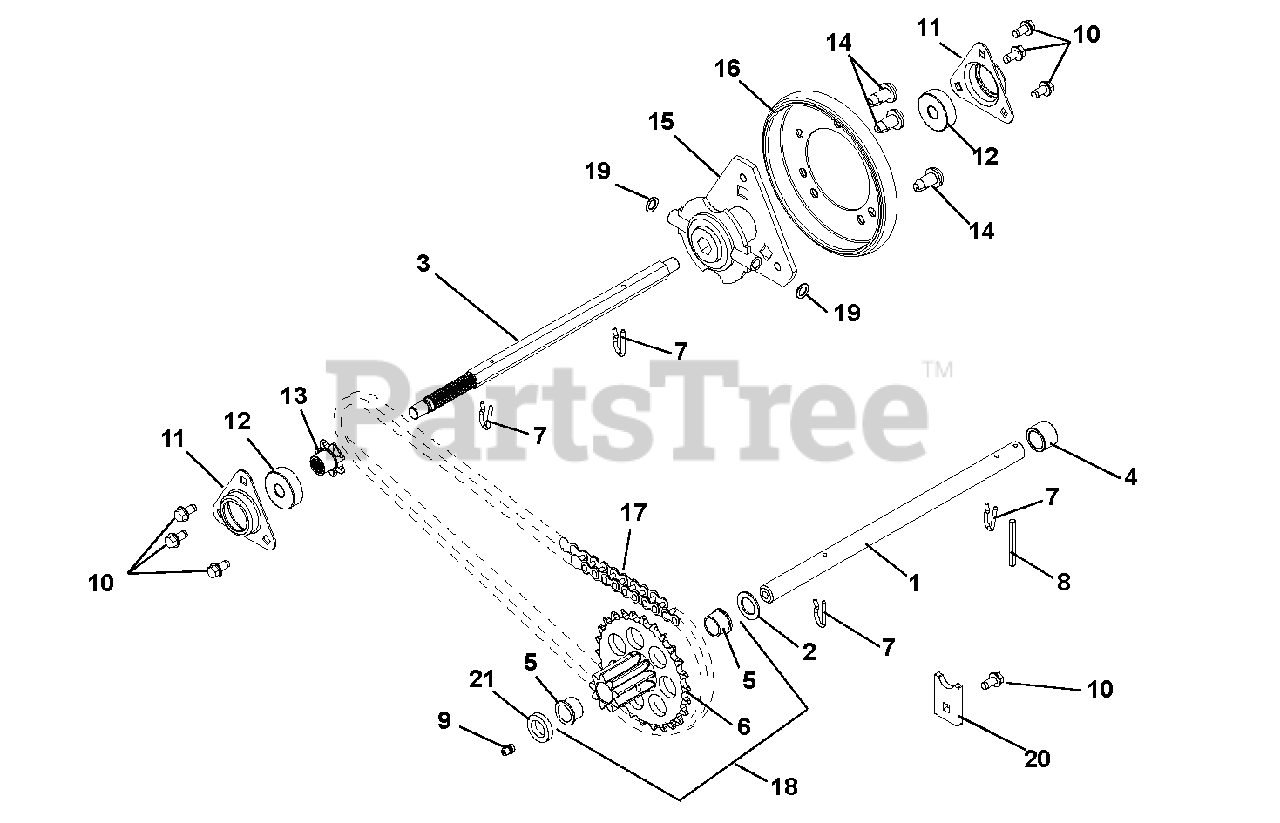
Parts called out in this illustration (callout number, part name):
1	Shaft, Pinion
2	Washer, Flat Steel .630 x 1.005 x .062
3	Shaft, Hex
5	Bushing, Flange (Included in Item 18)
6	Sprocket/Gear (Included in Item 18)
7	Pin, Spring Clip
8	Pin, Groove Type E .125 x 1.00
9	Zerk, Fitting .25 x .125 Drive-In
10	Screw, Tapping Hex Washer Head Thread Rolling .25-20 x .50
11	Flange, Bearing
13	Sprocket, Pinion
14	Screw, Tapping Serrated Round Head Torx .31-18 x .50
15	Carrier, Friction Disc
16	Friction Disc
17	Chain, Roller
18	Sprocket/Gear with Bushings (Includes Items 5 and 6)
19	Washer, Flat Steel .505 x 1.00 x .062
20	Tab, Anti-Rotation
21	Bushing, Sleeve
